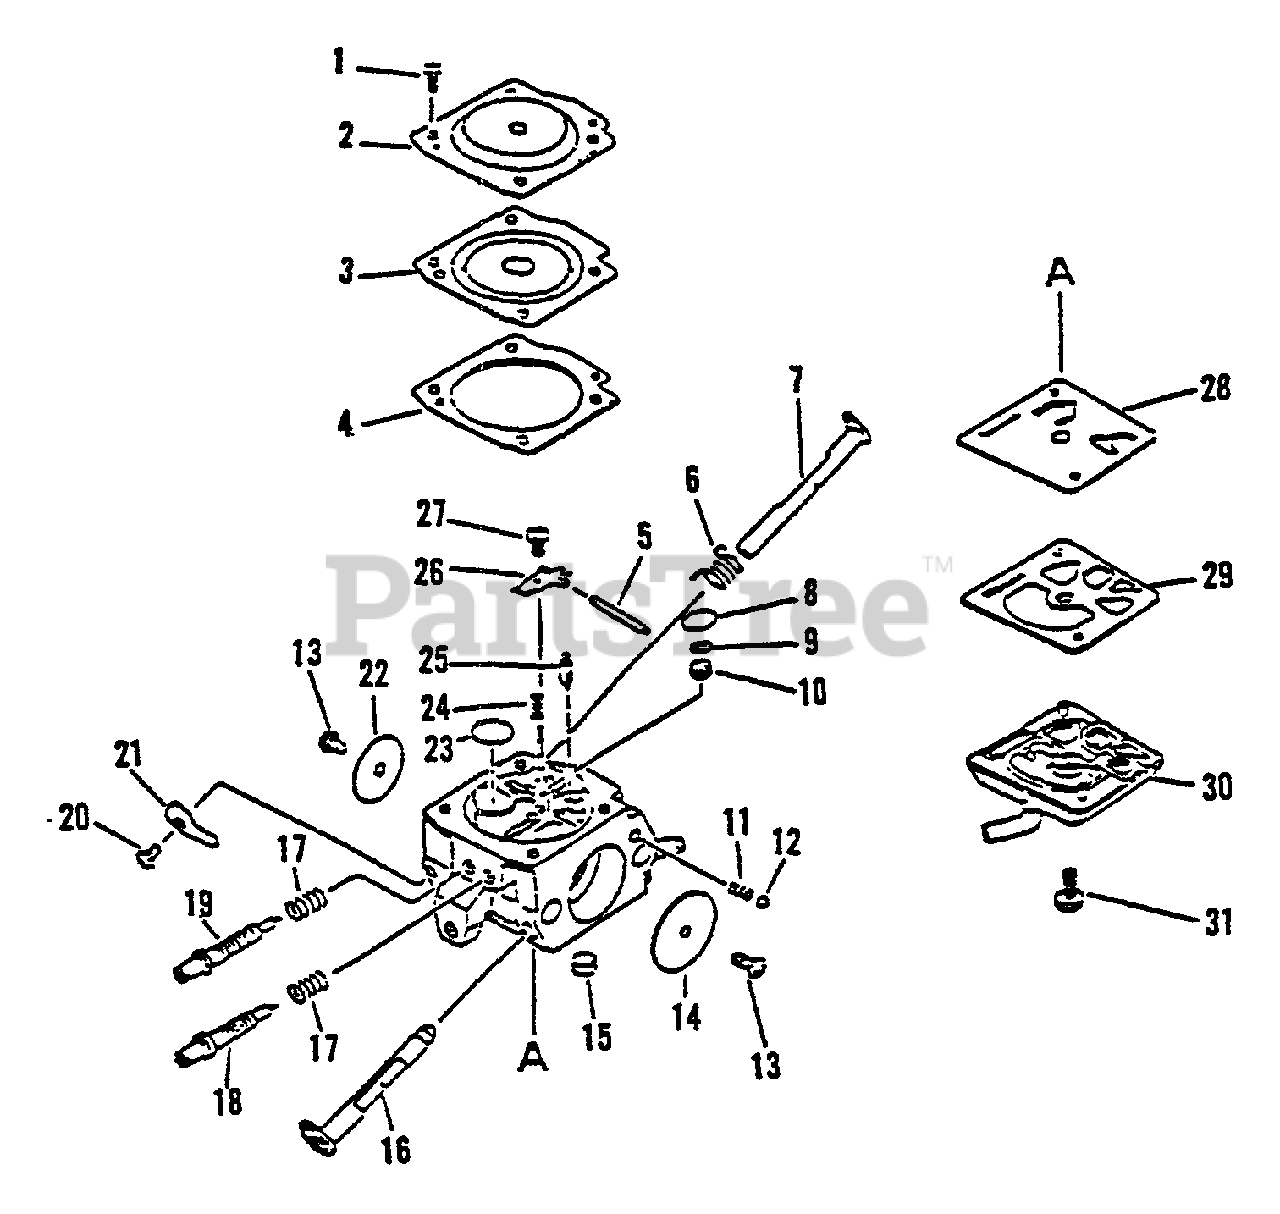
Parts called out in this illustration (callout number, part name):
1	SCREW
2	COVER, METERING
3	DIAPHRAGM
4	GASKET, METERING
5	PIN, METERING LEVER
6	SPRING, RETURN
7	SHAFT, THROTTLE
8	PLUG, WELCH
9	RING, RETAINING
10	STRAINER
11	SPRING
12	BALL, CHOKE
14	VALVE, CHOKE
15	STRAINER
16	SHAFT, CHOKE
17	SPRING
18	NEEDLE - HIGH SPEED
19	NEEDLE - LOW SPEED
21	LEVER, THROTTLE
22	VALVE, THROTTLE
23	PLUG, WELCH
24	SPRING
25	VALVE, NEEDLE
26	LEVER, METERING
27	SCREW
28	DIAPHRAGM, PURGE
29	GASKET, PURGE
30	BASE, PURGE
31	SCREW, PUMP COVER
